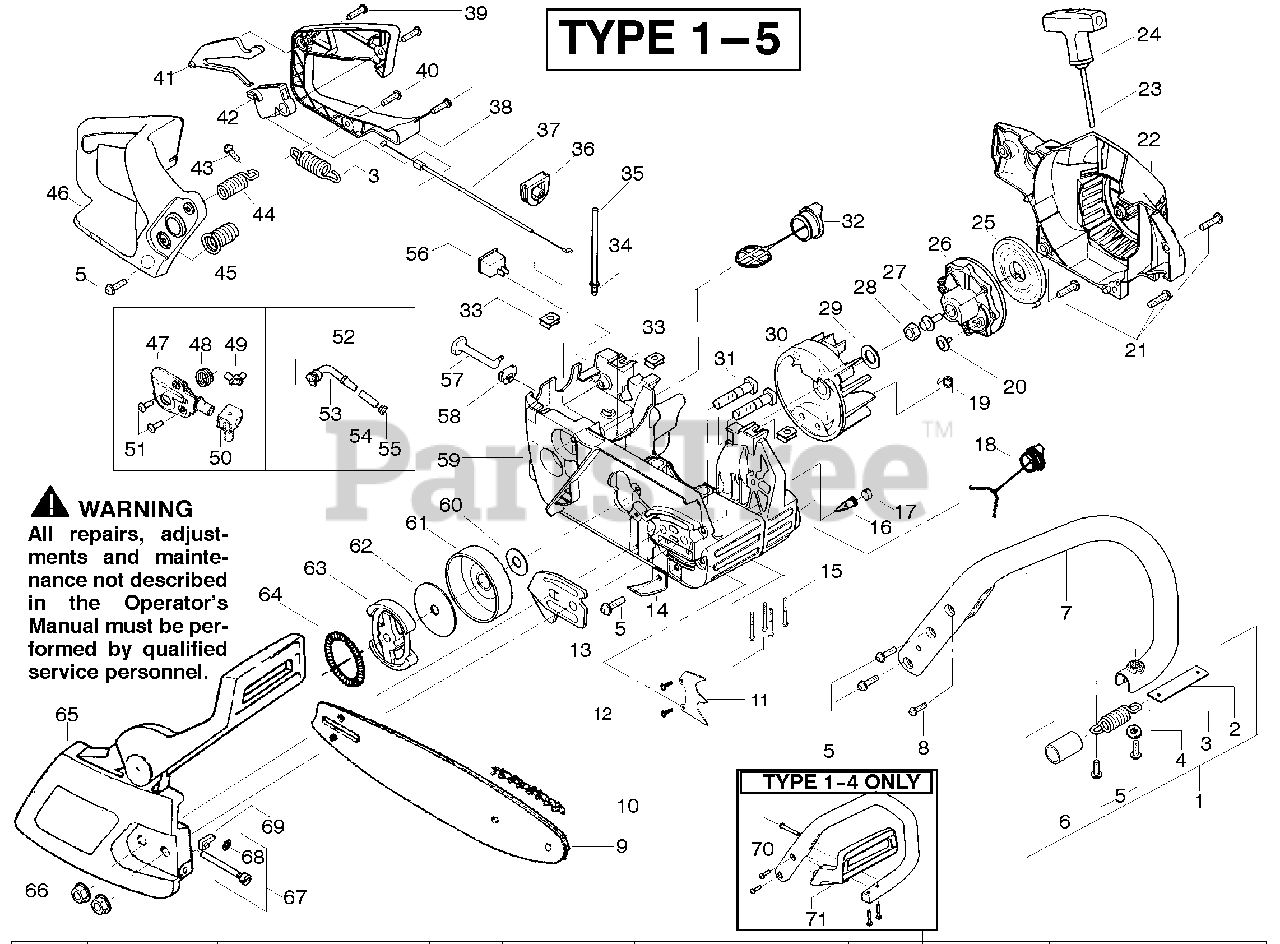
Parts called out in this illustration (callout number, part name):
1	Assy.- Isolator
2	Limiter Strap
3	Spring- Isolator
6	Sleeve-AV Spring
7	Front Handle
10	Chain-16"
10	Chain-18"
11	Kit-Spike Assy.
13	Plate-Bar Mounting
14	Chain Catcher
17	Plug-Bronze Vent
18	Assy-Oil Cap
19	Spring-Starter Dog
24	Handle-Starter
25	Spring-Recoil
26	Pulley-Starter
28	Nut- Flywheel
29	Washer- Flywheel
30	Assy- Flywheel
32	Assy-Fuel Cap
33	Nut- "U"-Type
34	Fitting- fuel line
35	Kit-Fuel line (large)
36	Grommet-Cable
37	Cable-Throttle
38	Cover-Rear Handle
41	Throttle Lockout
42	Trigger-Throttle
44	Kit- Isolator (Upper)
45	Assy. Isolator-lower
47	Kit-Oil Pump
48	Gear-Worm Spring
49	Elbow-Oil Pickup
52	Assy-Oil Pickup
54	Filter-Oil
55	Plug-Oil Filter
59	Assy-Chassis
60	Washer-Thrust
61	Assy.-Clutch Drum w/bearing
62	Washer-Clutch
63	Assy. Clutch
64	Spring-Clutch
65	Kit-Chain Brake
66	Nut-Bar Mounting
67	Kit-Bar Adjust
68	Retainer-Bar Adjust
69	Pin-Bar Adjust
70	Bolt-Handguard (Type 1-4 only)
71	Handguard (Type 1-4 only)
